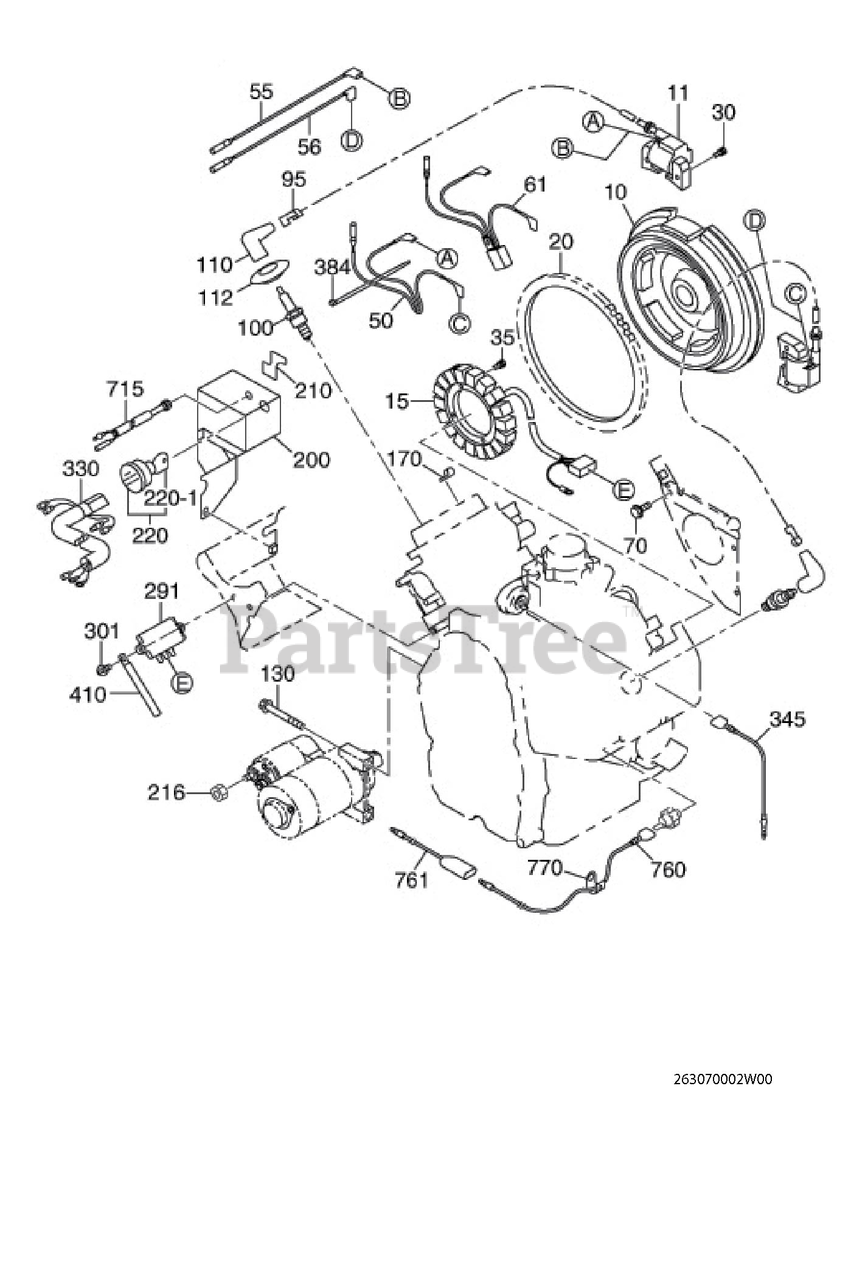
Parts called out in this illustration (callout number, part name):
11	IGNITION COIL CP
15	CHARGE COIL CP
30	BOLT AND WASHER AY
35	BOLT AND WASHER AY
50	WIRE CP(IG.COIL)
110	SPARK PLUG CAP
112	GROMMET, PLUGCAP
170	CLAMP
330	WIRING HARNESS CP
